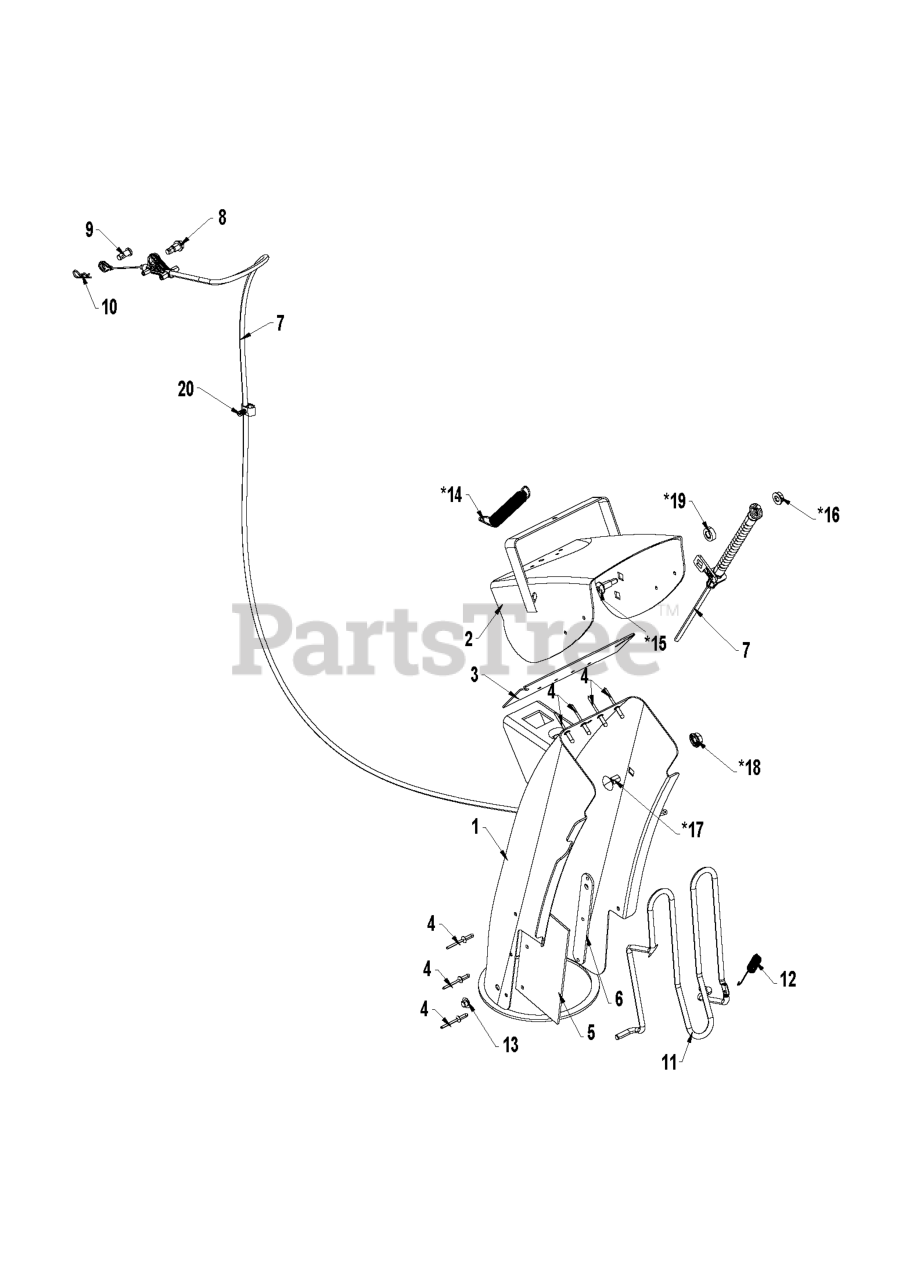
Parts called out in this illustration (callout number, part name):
1	ASM.CHUTE/DEFLECTOR.668
3	SEAL.DEFLECTOR
4	RIVET BLIND
5	SHIELD.SNOW.CHUTE
6	RP STRAP.SHEILD.RETAINER
8	BOLT SHOULDER_1/4-20_TRILOB
9	PIN CLEVIS .25 X ..4375
10	HAIRPIN.SOFT.ZINC.059X1.125
11	GUARD ROD CHUTE GUARD SHORT CL
12	SPRING.CHUTE.GUARD
13	NUT
20	CLIP.ROUTING DUAL
